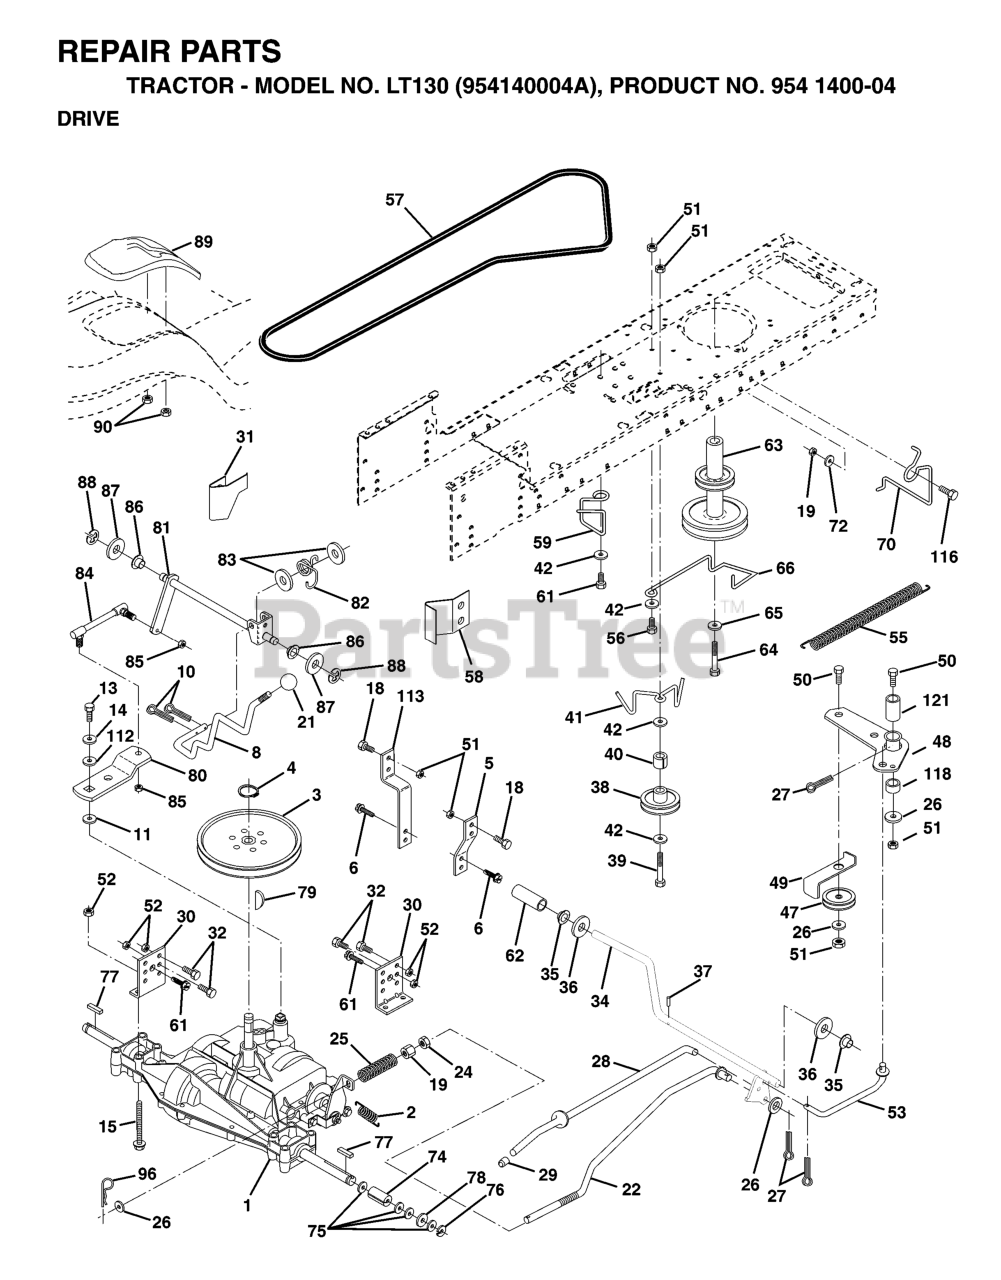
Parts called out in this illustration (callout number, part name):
2	SPRING,BRAKE RETURN
3	PULLEY TRANS
4	RETAINING RING LT
5	STRAP TORQUE
6	SCREW.THDROL.5/16-18X3/4.TTY
8	ROD SHIFT FENDER
10	PIN COTTER
11	WASH-SHFT PLT LT
13	BOLT 1/4-28X3/4
14	LOCKWASHER
15	BOLT HEX 5/16-18 GR 5
19	NUT
21	KNOB.DUCKHEAD.1/2
24	NUT
25	SPRING ROD LT
26	WASHER
27	COTTER PIN
28	ROD BRAKE PARK LT
29	PLUNGER CAP
30	BRACKET TRANSAXLE
31	KEEPER BELT LH
32	BOLT
34	SHAFT, FOOT PEDAL
35	BEARING.NYLON
37	DRIVE PIN
38	PULLEY.IDLER.FLAT
41	KEEPER, BELT IDLER
42	WASHER
47	IDLER PULLEY
48	BELLCRANK ASSEMBLY
49	RETAIN BELT
50	BOLT
52	LOCKNUT
53	LINK, CLUTCH LT
55	SPRING, RETURN LT
57	V-BELT
59	KEEPER CENTER SPAN
61	SCREW
62	PEDAL COVER T
63	PULLEY.ENG.CL.MECH.SLVR.LT/YT
64	BOLT
65	LOCKWASHER
66	KEEPER BELT ENGINE
70	KEEPER BELT ENG
72	WASHER
74	SPACER AXLE
77	SQUARE KEY
79	KEY STD (1373) DANA
81	SHAFT ASM CROSS 20"T
82	SPRING,TORSION
83	WASHER
84	ROD,TIE
85	NUT LOCK CENTER 1/4 -28 FNTHD
86	BUSHING.STEERING.ROD LTB-WSL
89	CONSOLE SHIFT
90	NUT.PUSH.3/16
96	RETAINER M
113	STRAP TORQUE LH LT
116	BOLT
118	SPACER BELLCRANK
121	NYLINER CLUTCHING
